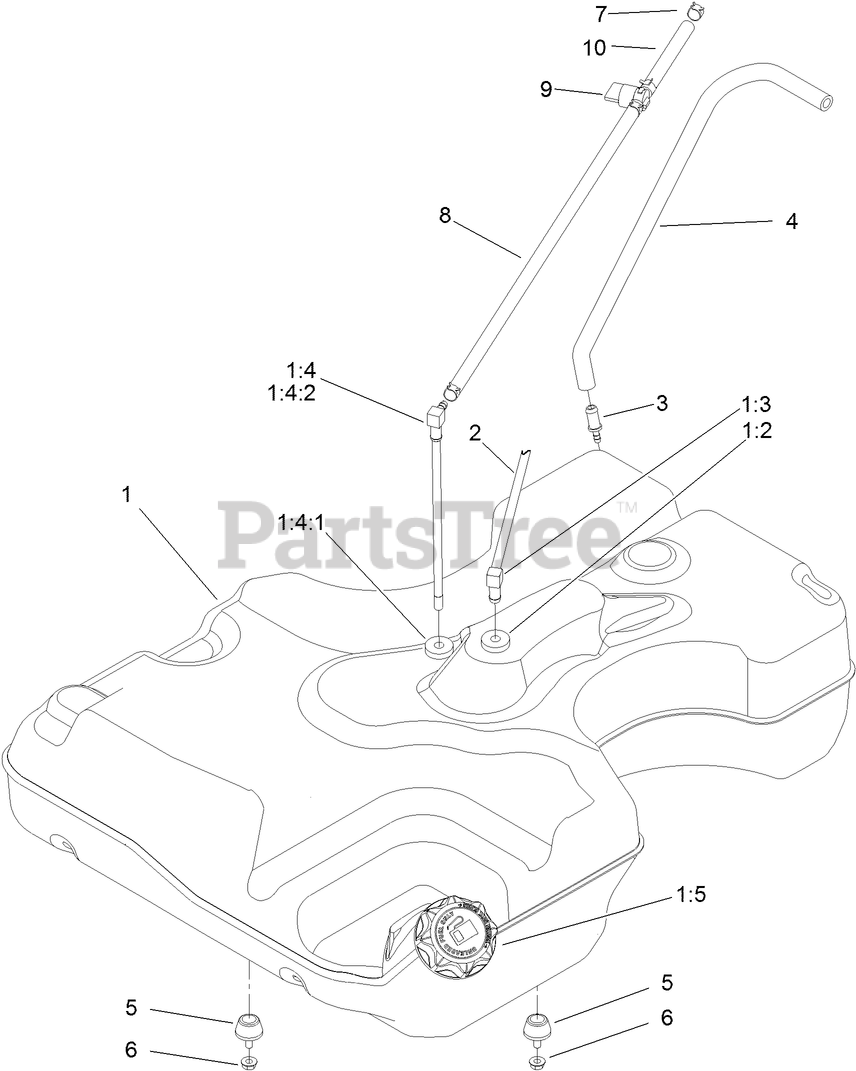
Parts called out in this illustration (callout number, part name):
1	FUEL TANK ASM
1:2	BUSHING
1:3	FITTING-90 ELBOW
1:4	FUEL LINE KIT
1:4:1	BUSHING
1:4:2	FITTING-FUEL (W/LINE AND SCREEN)
1:5	CAP-FUEL, RATCHETING
2	HOSE-FUEL
3	FITTING-STRAIGHT
4	HOSE-FUEL
5	BUMPER-RUBBER
6	NUT-HF
7	CLAMP-HOSE
8	HOSE-FUEL
9	VALVE-FUEL
10	HOSE-FUEL
